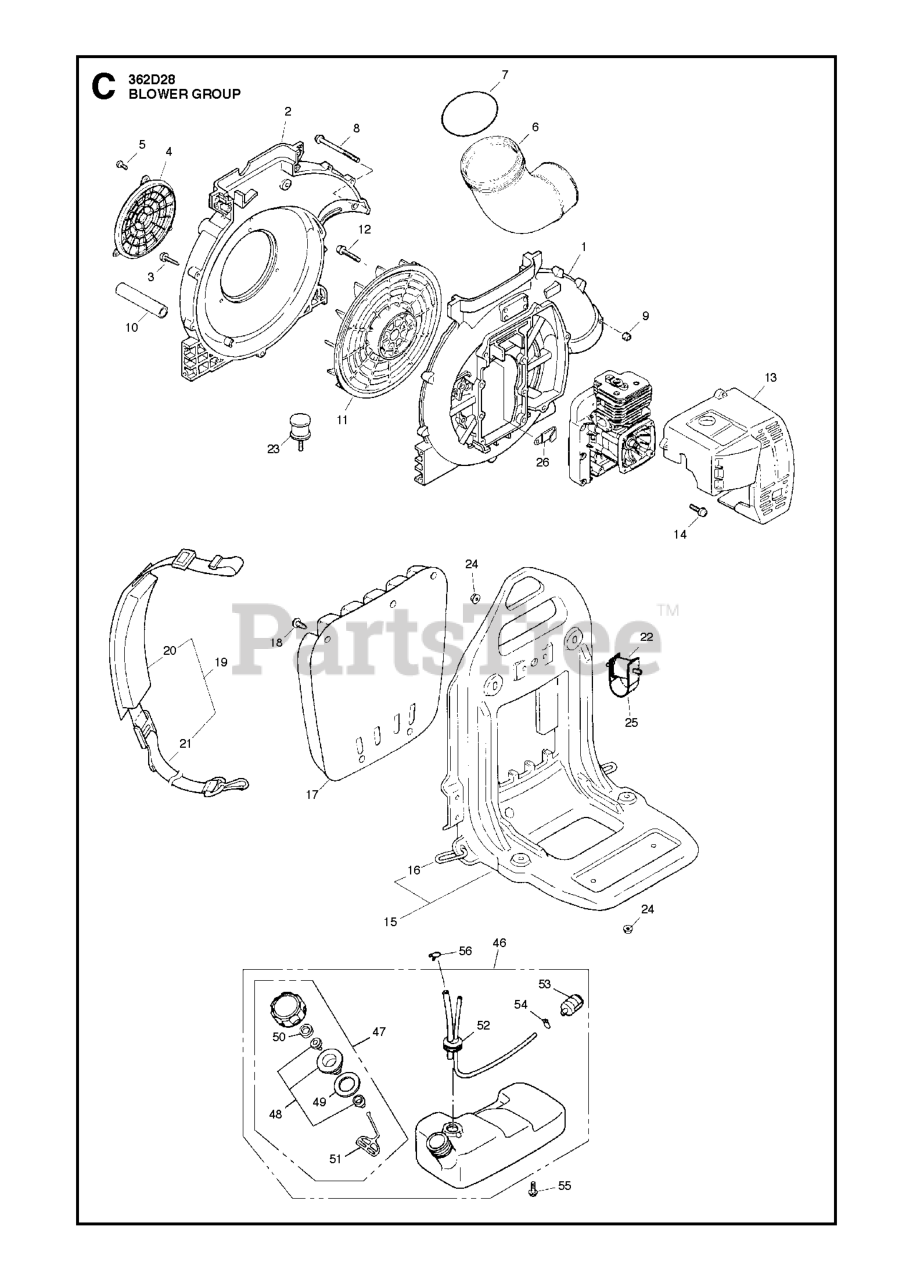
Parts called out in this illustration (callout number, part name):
10	TUBE
47	ASSY FUEL CAP
53	FILTER ASSY
